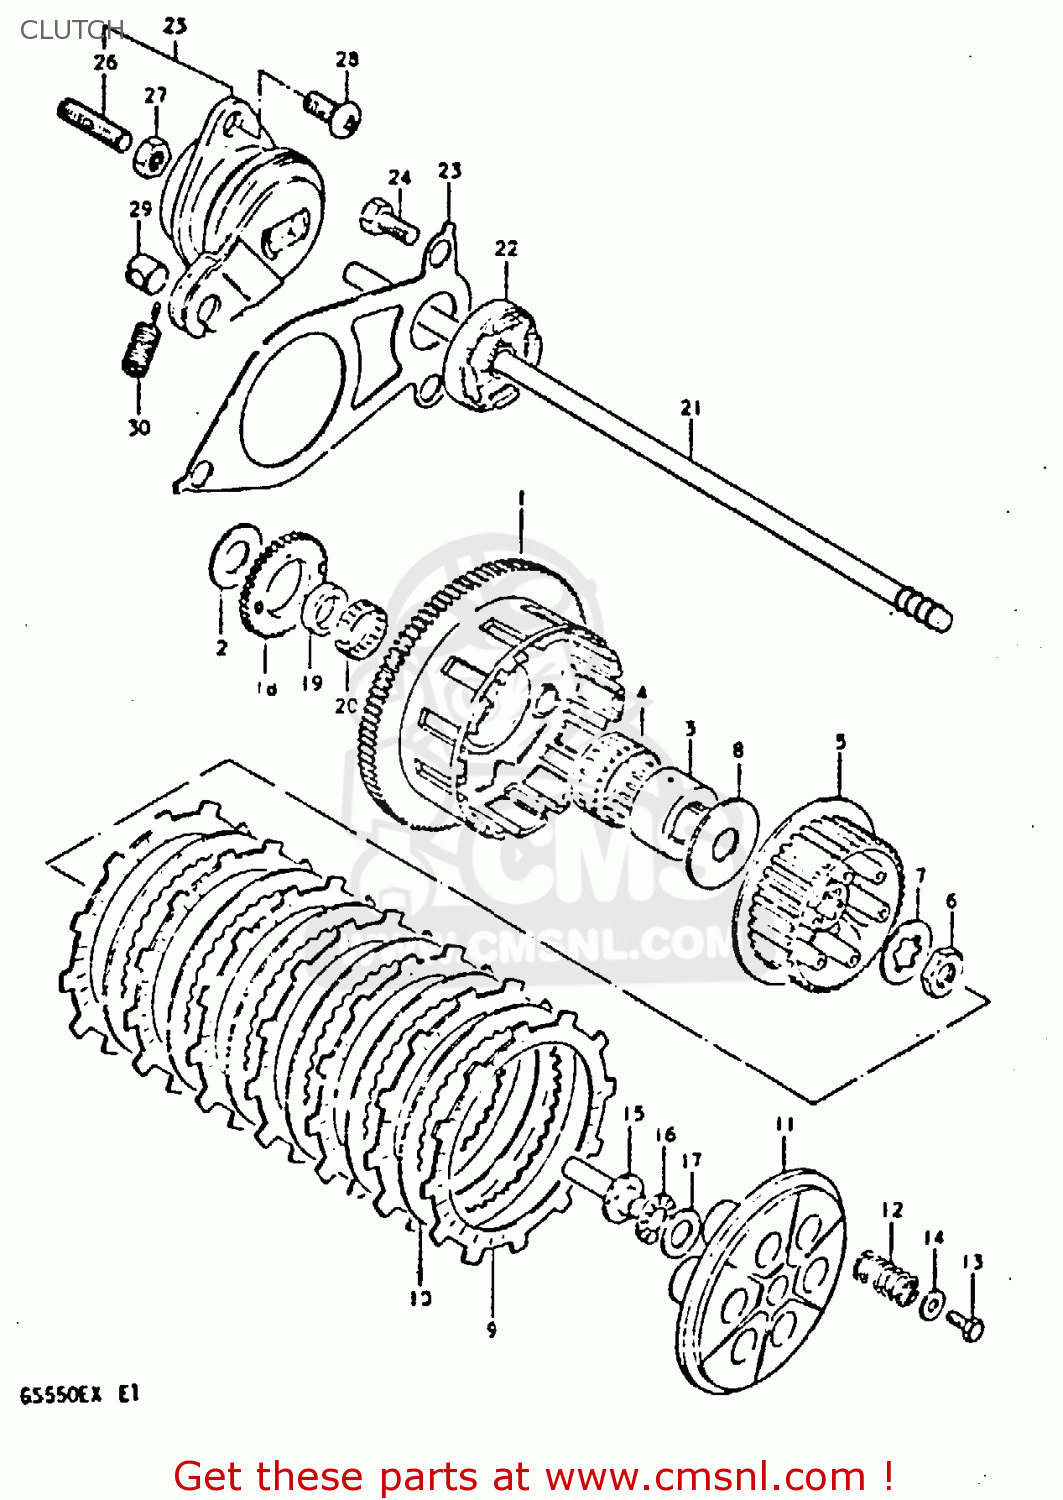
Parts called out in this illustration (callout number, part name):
1	GEAR ASSEMBLY,PRIMARY DRIVE NT:87
2	WASHER
3	SPACER,PRIMARY DRIVEN
4	BEARING
5	HUB,CLUTCH SLEEVE
6	NUT
7	WASHER,LOCK
8	WASHER(25X66X3.5)
9	PLATE,CLUTCH DRIVE (NAS)
10	PLATE,CLUTCH DRIVEN (NAS)
11	DISC,CLUTCH PRESSURE
12	SPRING
13	BOLT, UPPER
14	WASHER
15	PIECE,CLUTCH PUSH
16	BEARING(15X28X2)
17	WASHER
18	GEAR,ENG OIL PUMP DRIVE(NT:38)
19	SPACER,OIL PUMP DRIVE GEAR
20	BEARING(36X40X10)
21	ROD,CLUTCH PUSH
22	OIL SEAL
23	PLATE,CLUTCH PUSH ROD
24	BOLT
25	SCREW ASSEMBLY,CLUTCH RELEASE
26	SCREW
27	NUT 6MM
28	SCREW 6X12
29	PIECE,RELEASE ARM END
30	SPRING
